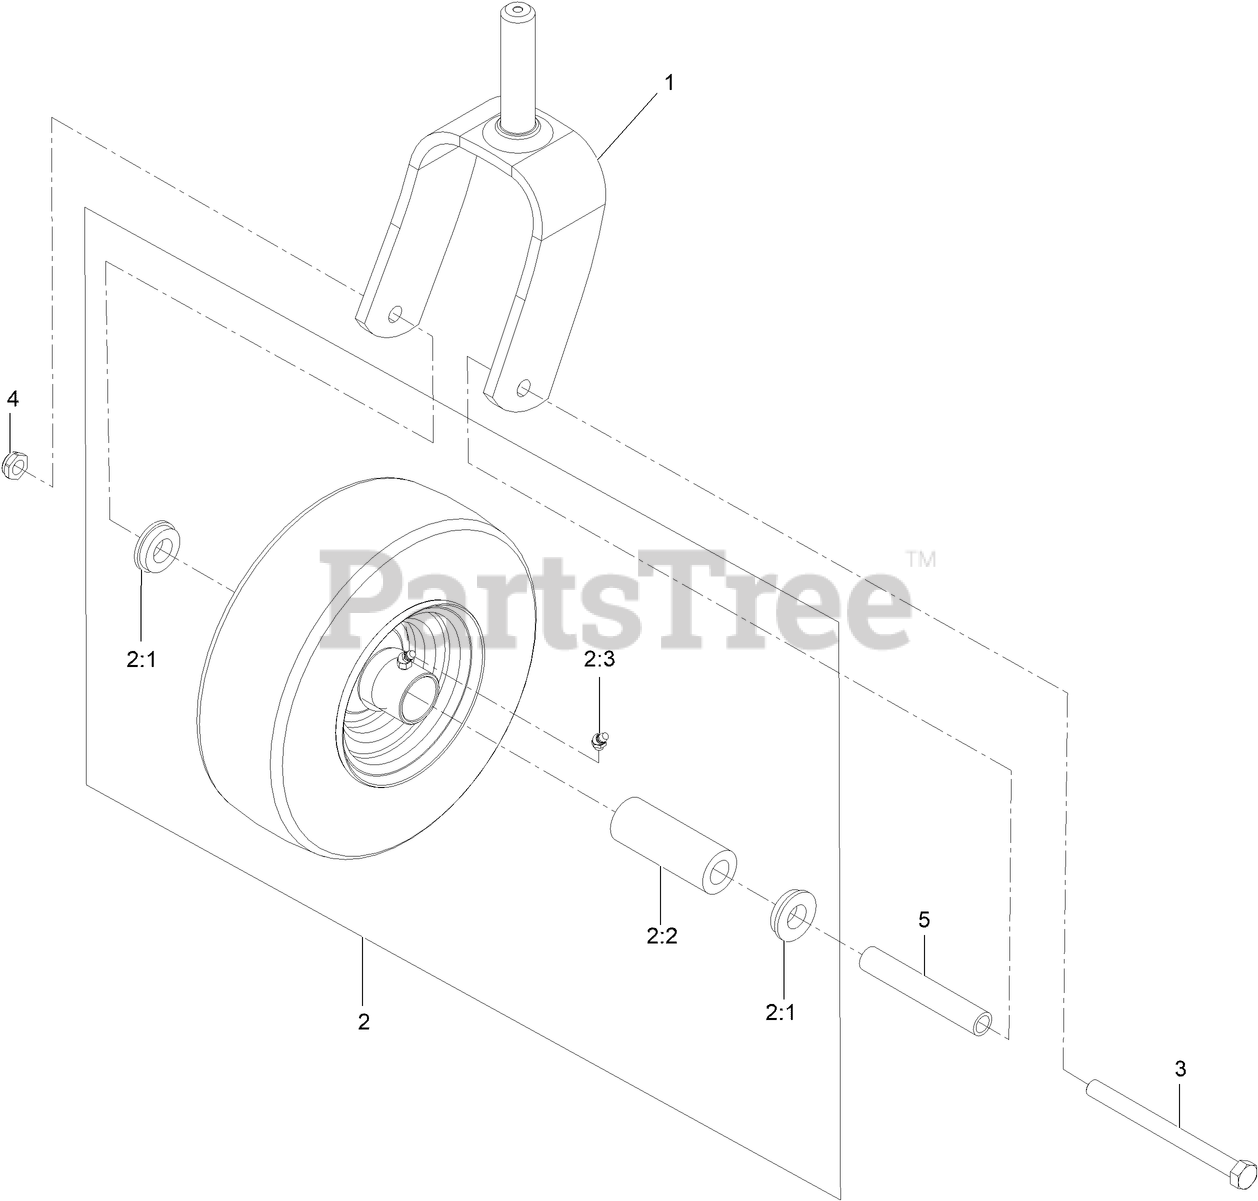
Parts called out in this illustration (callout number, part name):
1	FORK-CASTER
2	WHEEL AND TIRE ASM
2:1	BUSHING
2:2	BEARING
2:3	FITTING-GREASE
3	SCREW-HH
4	NUT-HEX
5	SPACER
